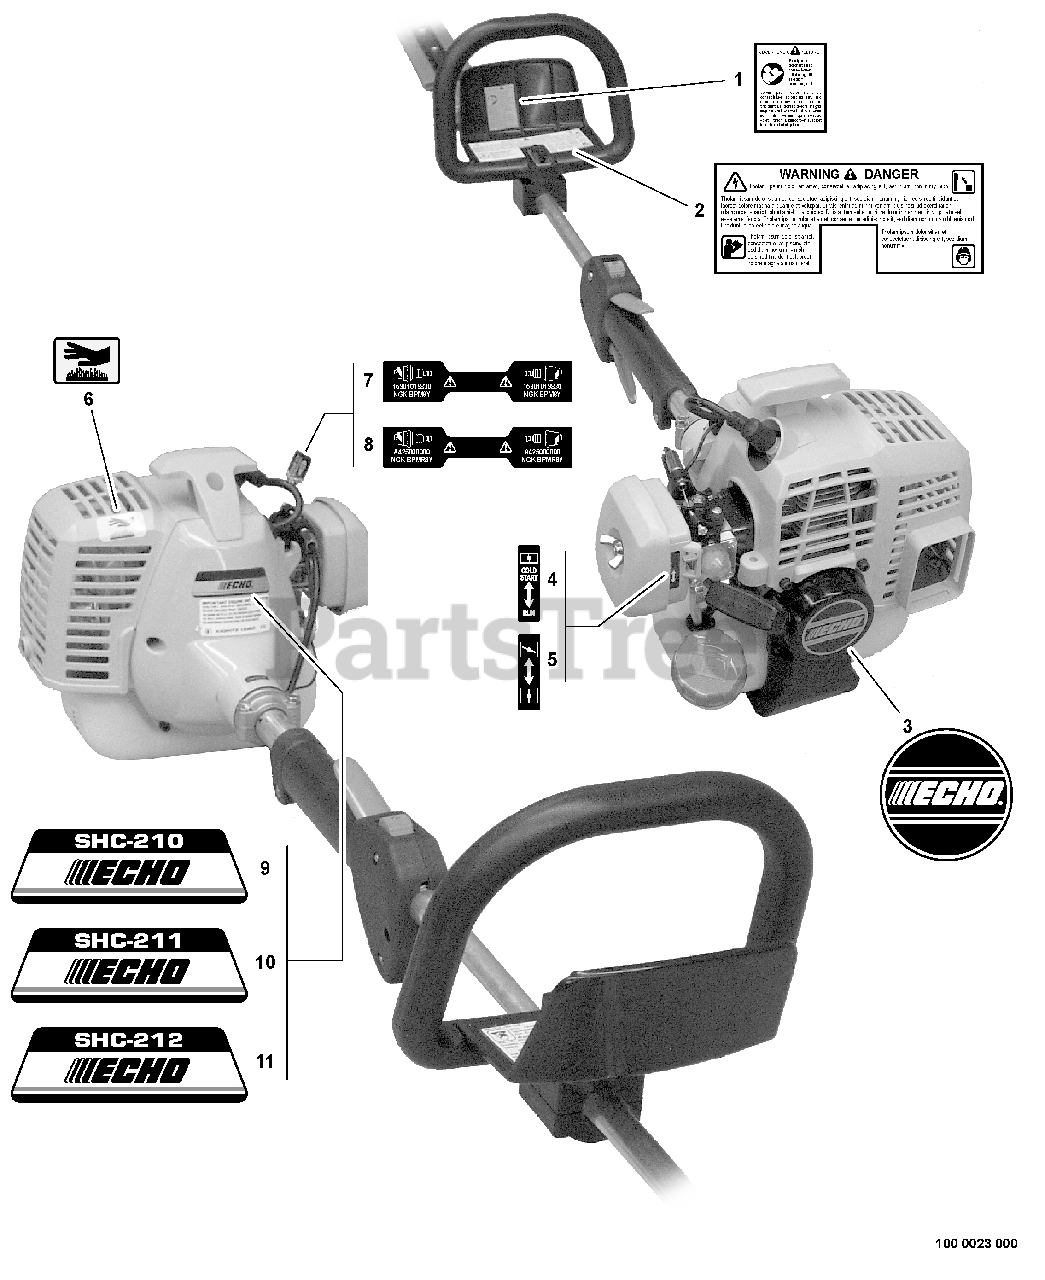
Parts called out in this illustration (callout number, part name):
1	LABEL - CAUTION -- SPANISH
2	LABEL - WARNING
3	LABEL - ECHO
4	LABEL - CHOKE
5	LABEL - CHOKE
6	LABEL - HOT SURFACE
7	LABEL - SPARK PLUG -- BPM-8Y
8	LABEL - SPARK PLUG -- BPMR-8Y
9	LABEL - MODEL SHC-210
10	LABEL - MODEL SHC-211
11	LABEL - MODEL SHC-212
